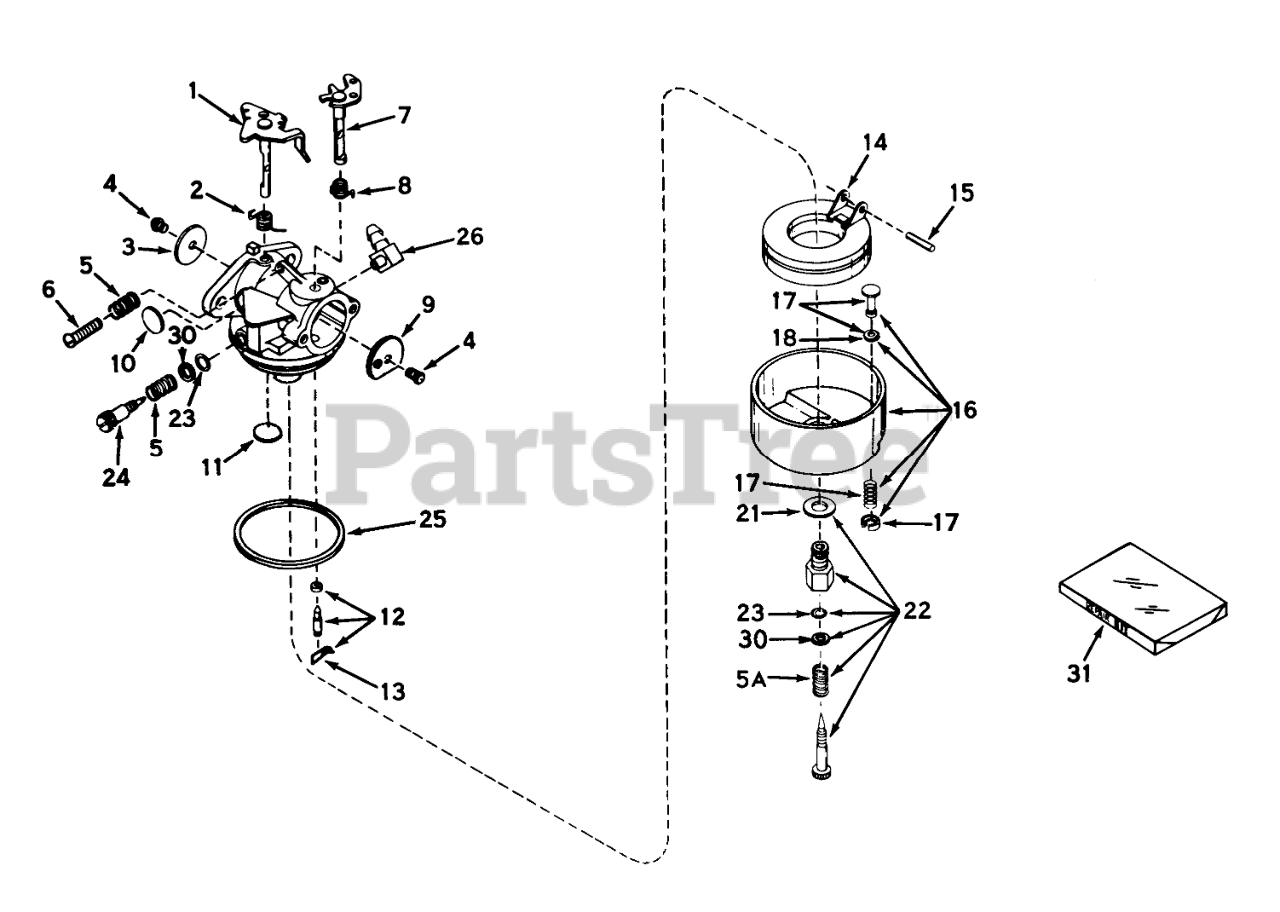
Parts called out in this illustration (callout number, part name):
1	Shaft/Lever-Throttle
2	Spring, Return
3	Shutter-Throttle
4	Screw-Shutter
5	Spring-Tension
6	Screw-Throttle Crack Screw / Idle Speed
7	Shaft& Lever Assy., Choke
8	Spring, Choke return
9	Shutter-Choke
10	Plug-Welch, Idle Mixture Well
11	Plug-Welch, Atmospheric Vent
12	Inlet Needle, Seat & Clip Assy. (Incl. No. 13)
13	Clip-Spring
14	Float,Carburetor
15	Shaft-Float
16	Bowl & Drain Assy., Float (Incl. No. 17)
17	Plunger Assy., Drain (Incl. No. 18)
18	Gasket-Plunger, Drain
21	Washer-Bowl Nut
22	Adjustment Screw Assy., Main (Incl. Nos. 5A, 21, 23 & 30)
23	"O"Ring
24	Screw, Idle Adj.
25	O Ring-Bowl, Float
26	Fitting Fuel Inlet
31	Repair Kit
